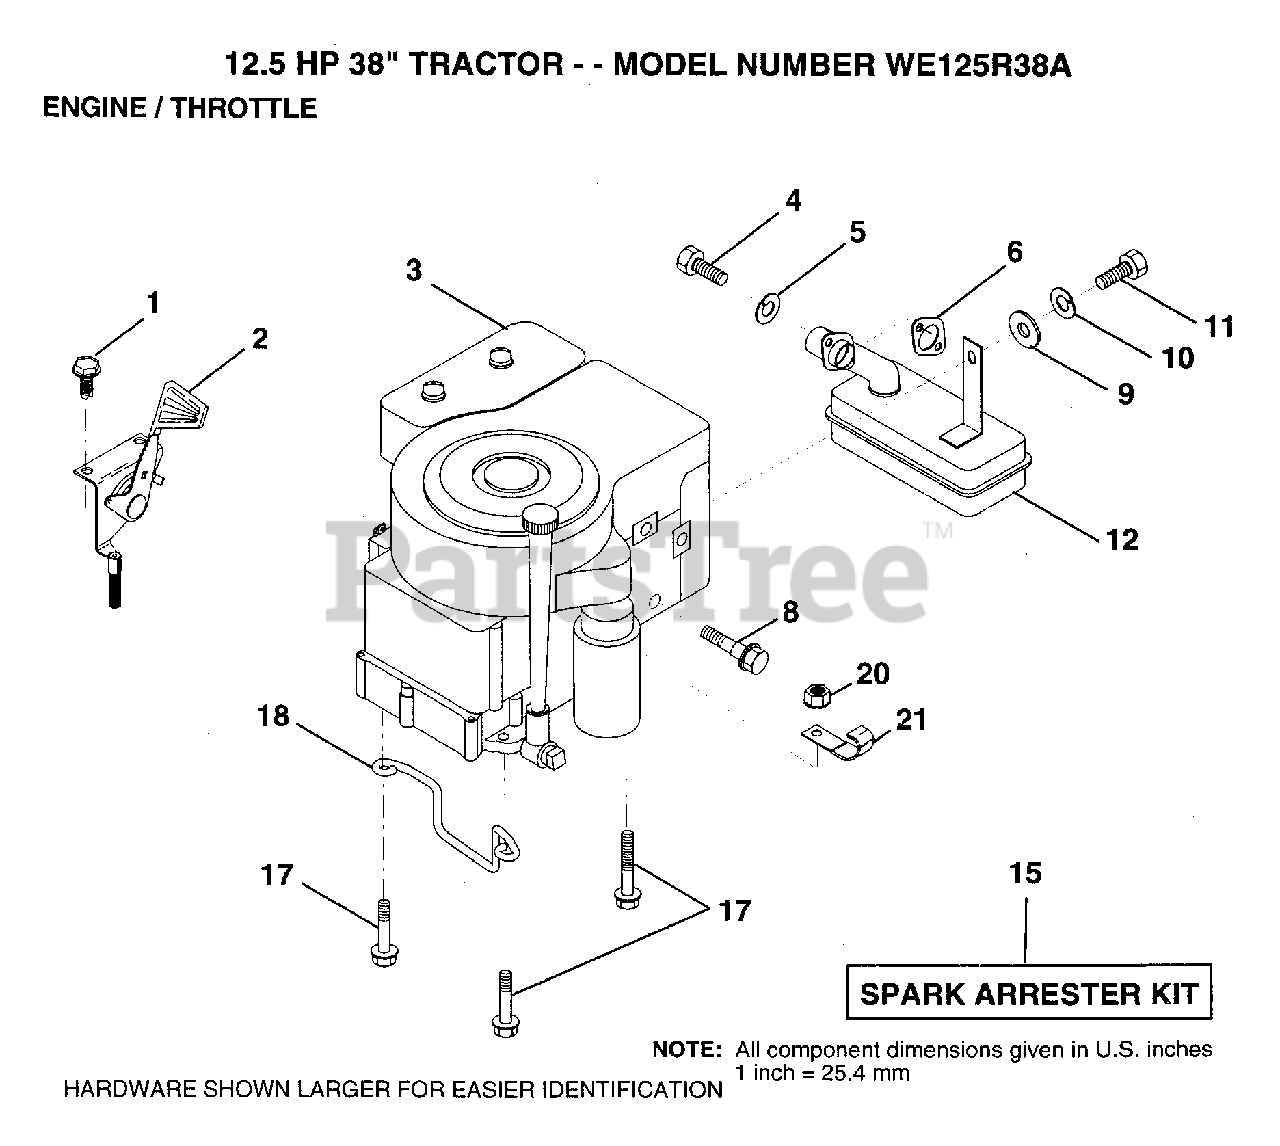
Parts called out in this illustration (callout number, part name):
1	SCREW.1/4-20X1/2
2	"CONTROL,THROTTLE"
3	ENGINE, B&S
4	SCREW
5	LOCKWASHER
8	BOLT T
10	LOCKWASHER
12	MUFFLER
17	SCREW LT
18	"KEEPER,DR BELT GR"
20	NUT
21	CLIP T
